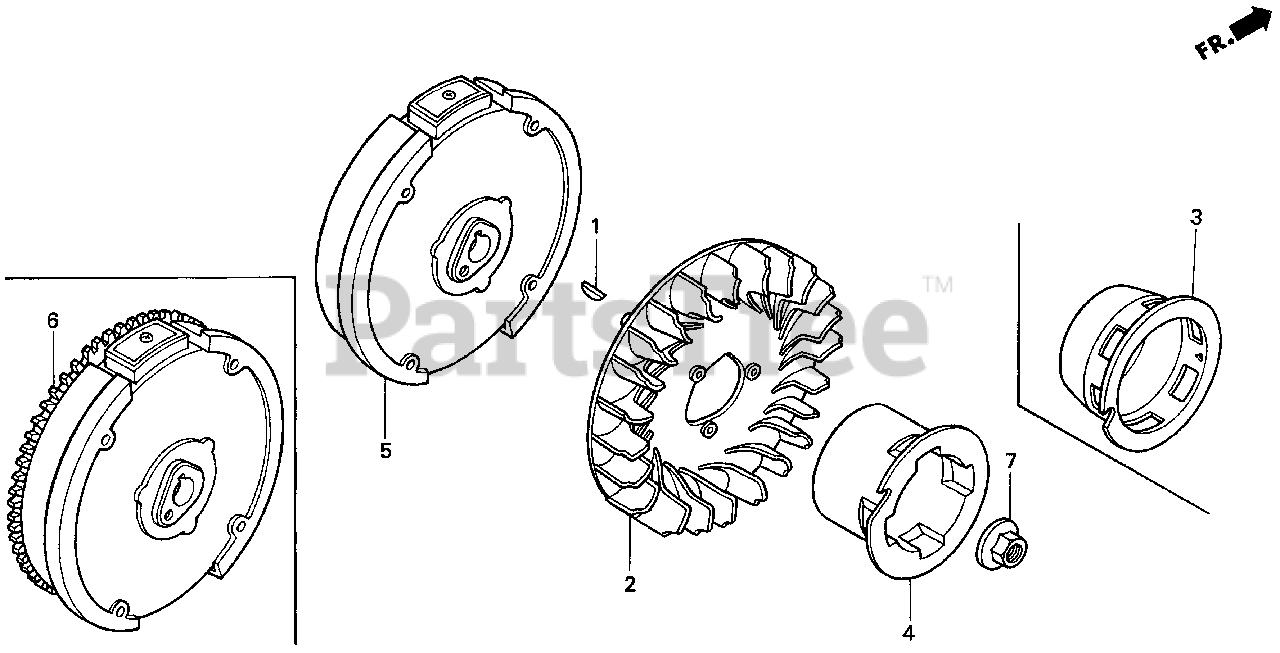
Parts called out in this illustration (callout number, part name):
1	KEY, SPECIAL WOODRUFF (25X18)
2	FAN, COOLING
3	PULLEY, STARTER
5	FLYWHEEL
7	NUT, SPECIAL (14MM)
